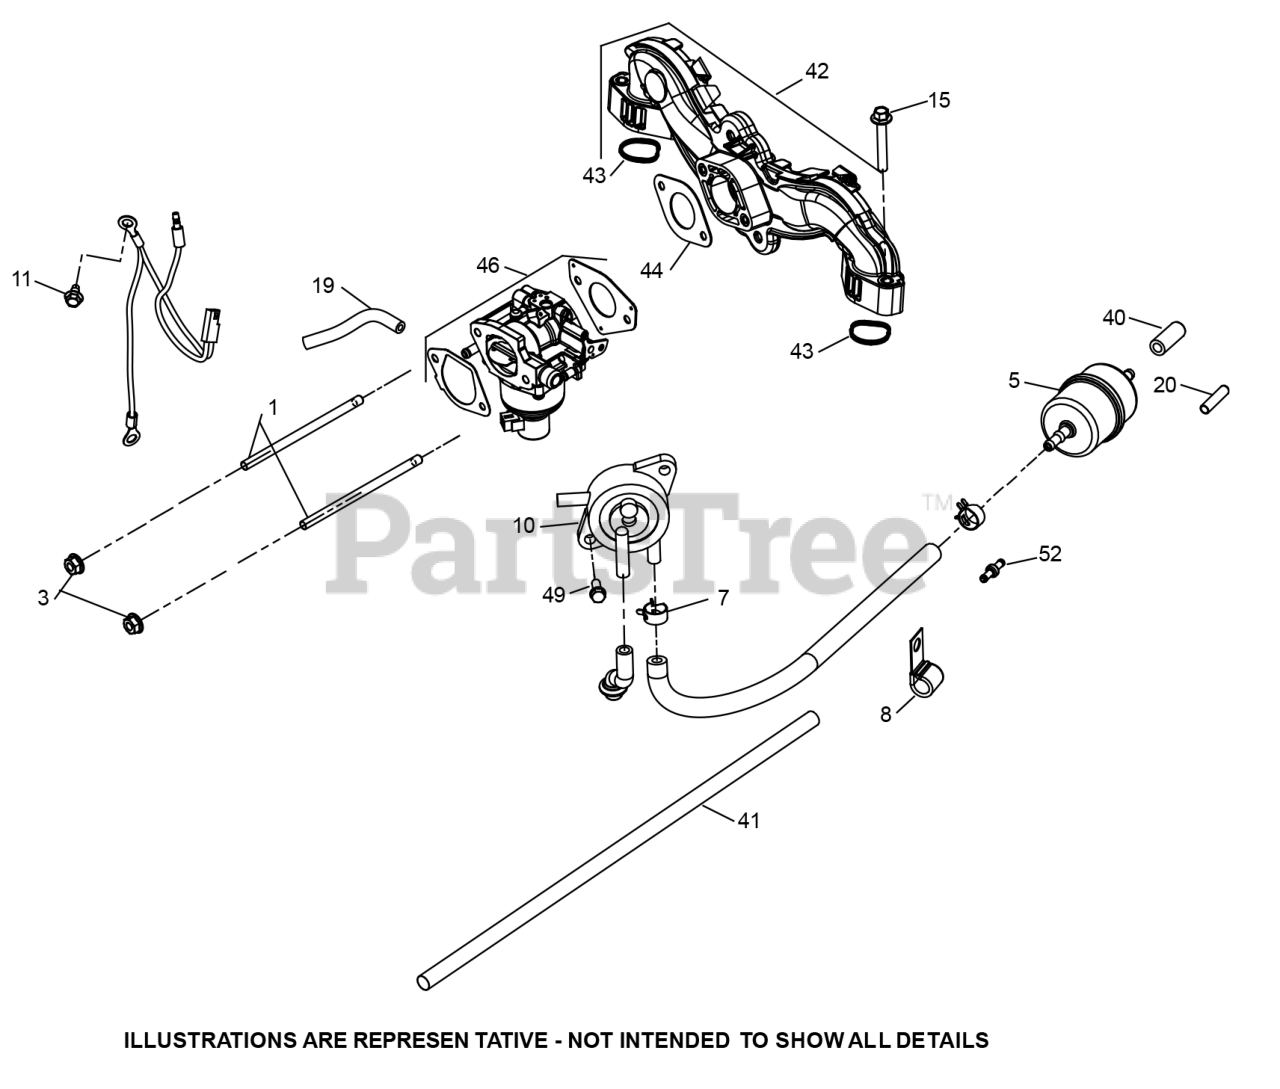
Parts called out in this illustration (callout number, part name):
1	CARB MOUNTING STUD
3	HEX FLANGE NUT
5	FUEL FILTER
8	CLIP
15	HEX SCREW FLANGE
19	EVAPORATIVE HOSE
41	SLEEVE-ANTI ABRASION
42	INTAKE MANIFOLD W/GASKETS
43	O-RING, INTAKE PORT
44	GASKET, CARBURETOR (PIM, CV)
46	CARBURETOR KIT NIKKI
49	HEX HEAD SCREW
